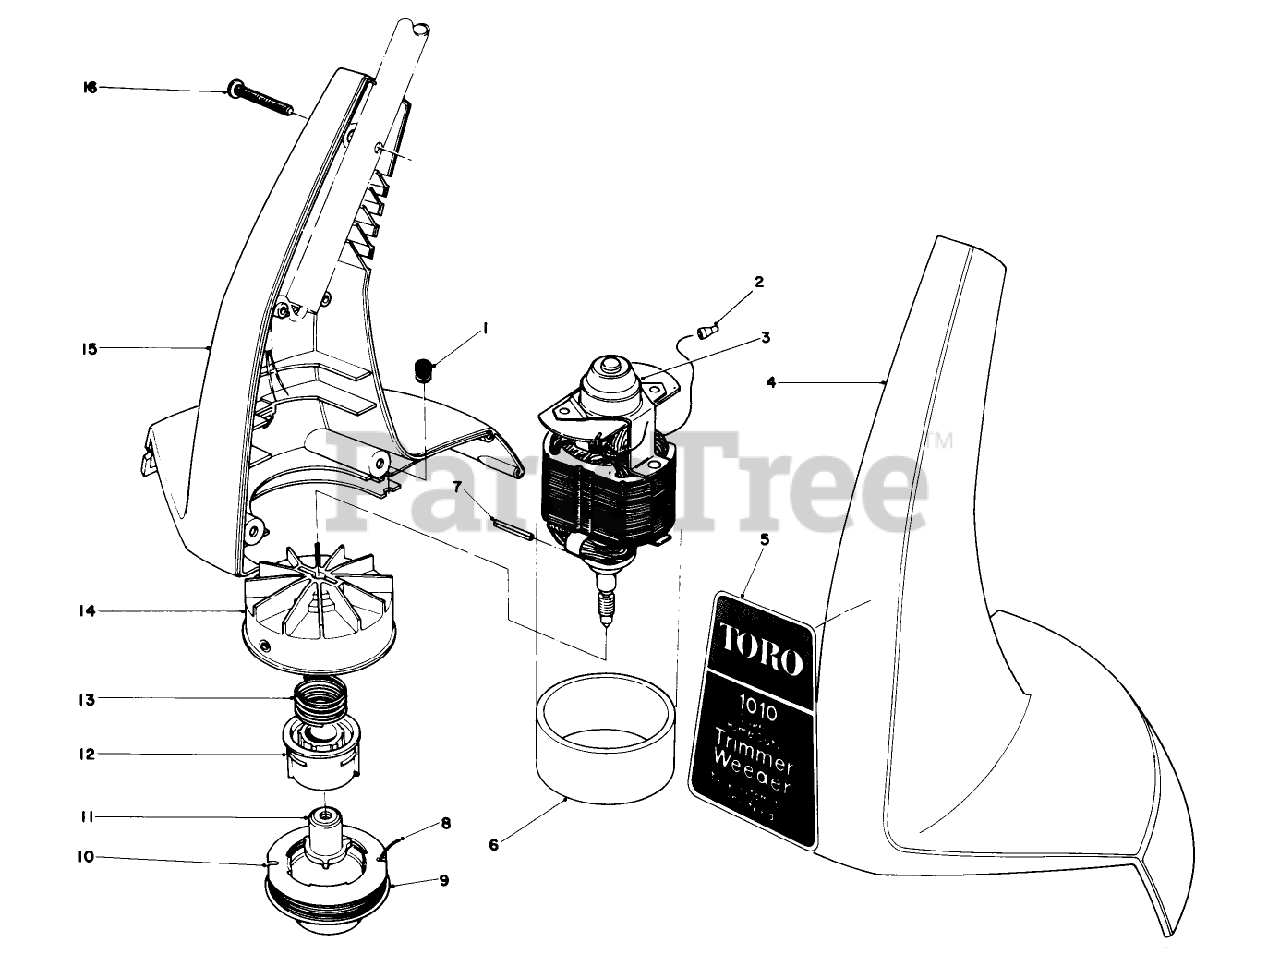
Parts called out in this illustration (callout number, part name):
1	GROMMET
2	CONNECTOR WIRE JOINT
3	Motor
4	Housing-L.H.
5	Decal-Housing
6	DAMPENING SLEEVE
7	COIL PIN
8	Line-Cutting (30- .05 Dia.)
9	SPOOL CAP
10	Prewound Spool Cap
11	DRIVER DETENT
12	CORE - SPOOL
13	SPRING-COMPRESSION
14	FAN HUB ASM
15	Housing Assembly-R.H.
16	Screw
